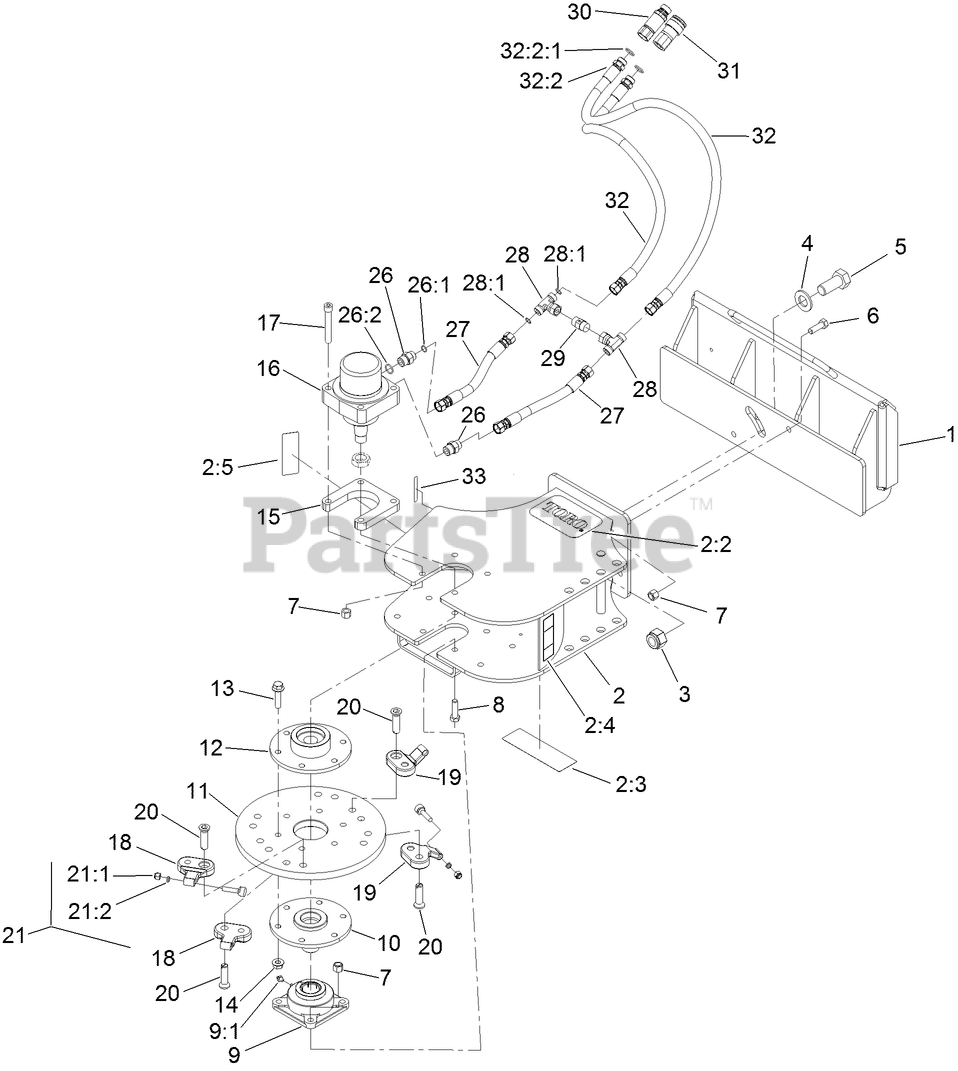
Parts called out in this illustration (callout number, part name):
1	PLATE-ATTACH, QUICK
2	GRINDER FRAME ASM
2:2	DECAL
2:3	DECAL-SAFETY, GRINDER
2:4	DECAL-WARNING
2:5	DECAL-DANGER
3	NUT-HEX, NI
4	WASHER-FLAT
5	SCREW-CAP
6	SCREW-HH
7	NUT-LOCK, NI
8	SCREW-HH
9	BEARING
9:1	FITTING-GREASE
10	SHAFT-STUB
11	WHEEL-GRINDER, STUMP
12	HUB-DRIVE
13	SCREW-HHF
14	NUT-HHF
15	PLATE- SPACER
16	HYD MOTOR ASM
17	SCREW-HSH
18	POCKET-STRAIGHT
19	POCKET-ANGLED
20	BOLT-HSH, RH
21	GRINDER TOOTH ASM
21:1	NUT-LOCK, NI
21:2	SPACER-TOOTH
26	FITTING-STRAIGHT
26:1	O-RING
26:2	O-RING
27	HYD HOSE ASM
28	FITTING-TEE
28:1	O-RING
29	VALVE-CHECK
30	NIPPLE-CONNECT, PRESSURE
31	COUPLER-FACE, FLUSH
32	HYD HOSE ASM
32:2	FITTING-STRAIGHT
32:2:1	O-RING
33	DECAL-WARNING
